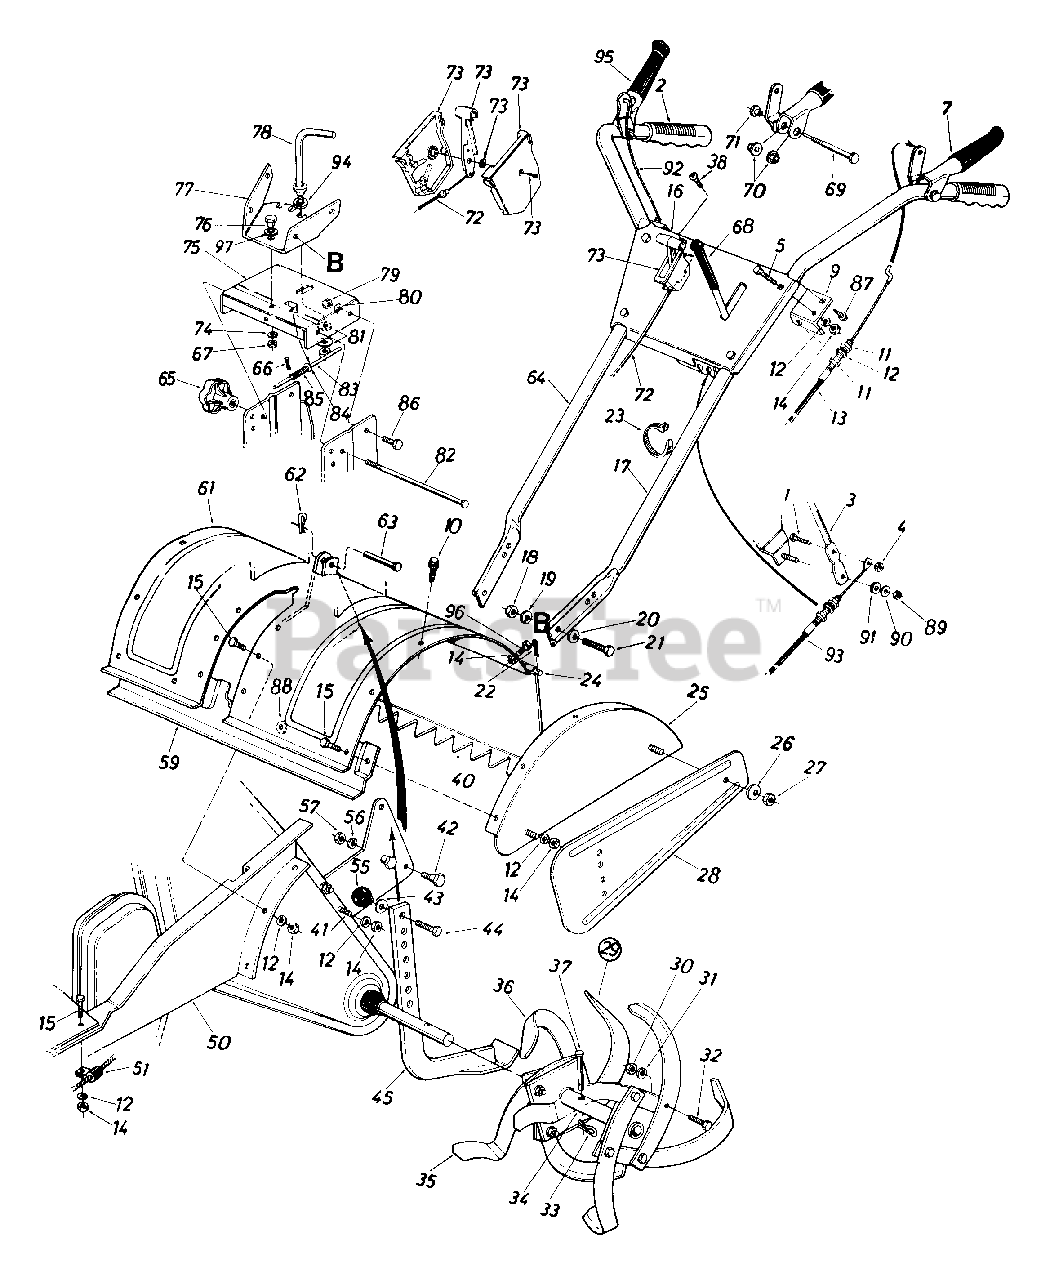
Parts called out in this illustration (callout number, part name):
1	Hex Bolt 1/4-28 x .75" Lg.
2	Grip
3	Clutch Lever
4	Hex Cent. L-Nut 1/4-28 Thd.
5	Carr. Bolt 5/16-18 x 1.75"
7	Clutch Grip Ass'y. - L.H.
9	Clutch Cable Bracket
10	Hex Wash. S-Tap Scr. 5/16-18 x .62" Lg.
11	Hex Nut 5/16-24 Thd.
12	L-Wash. 5/16" I.D.
13	Clutch Control Cable (Tines)
14	Hex Nut 5/16-18 Thd.
15	Hex Bolt 5/16-18 x .75" Lg.
19	L-Wash. 3/8" I.D.
20	Bell-Wash. 3/8" I.D.
21	Hex Bolt 3/8-16 x 1" Lg.
22	Cotter Pin 3/32" Dia. x 3/4"
23	Cable Tie
24	Tiller Flap Rod
27	Hex Nut 5/16-18 Thd.
31	L-Wash. 3/8" I.D.
32	Hex Bolt 3/8-24 x 1.25" Lg.
33	Hairpin Cotter
38	Truss Mach. AB-Tap Scr. #10 x .5" Lg.
41	Hex Bolt 5/16-18 x 1.0" Lg.
42	Shld. Bolt 1/2" Dia. x .43"
43	Fl-Wash. 3/8" I.D. x 5/8" O.D.
44	Hex Bolt 3/8-16 x 3/4" Lg.
55	Ball Knob 11/4" Dia.
56	L-Wash. 3/8" I.D.
57	Hex Nut 3/8-16 Thd.
63	Clevis Pin 3/8" Dia.
66	Cotter Pin 1/16" Dia. x .75"
67	Hex Cent. L-Nut 3/8-16 Thd.
69	Shoulder Bolt .375" Dia. x 1.37" Lg.
70	Hex Flange Plastic Bearing
71	Shoulder Nut 1/4-20 Thd.
72	Throttle Control Wire
73	Throttle Control Box Ass'y.
74	Bell-Wash. .40" I.D. x 1.13"
79	Hex Cent, L-Nut 3/8-16 Thd.
80	Bell-Wash. .40" I.D. x .88"
81	Bell-Wash. 1/2" I.D. x 1.00"
82	Lock Pin 5/16" Dia. x 8"
83	Lower Sliding Ass'y.
84	Fl-Wash. .291" I.D. x .62"
85	Compression Spring 1" Lg.
86	Shoulder Bolt 1/2" Dia. x .170" Lg.
87	Hex Wash. S-Tap Scr. 1/4-20 x .50" Lg.
88	Bell-Wash. 5/16" I.D.
89	Hex Cent. L-Nut 5/16-18 Thd.
90	Fl-Wash. .344" I.D. x .87"
91	Rubber Wash. .33 I.D. x .87"
92	Control Cable (Forward)
93	Control Cable (Reverse)
94	Fl-Wash. .62" I.D. x 1.57"
95	Clutch Grip Ass'y. - R.H.
96	Hex Bolt 5/16-18 x 1.25"
97	Fl-Wash. .64" I.D. x .94"
